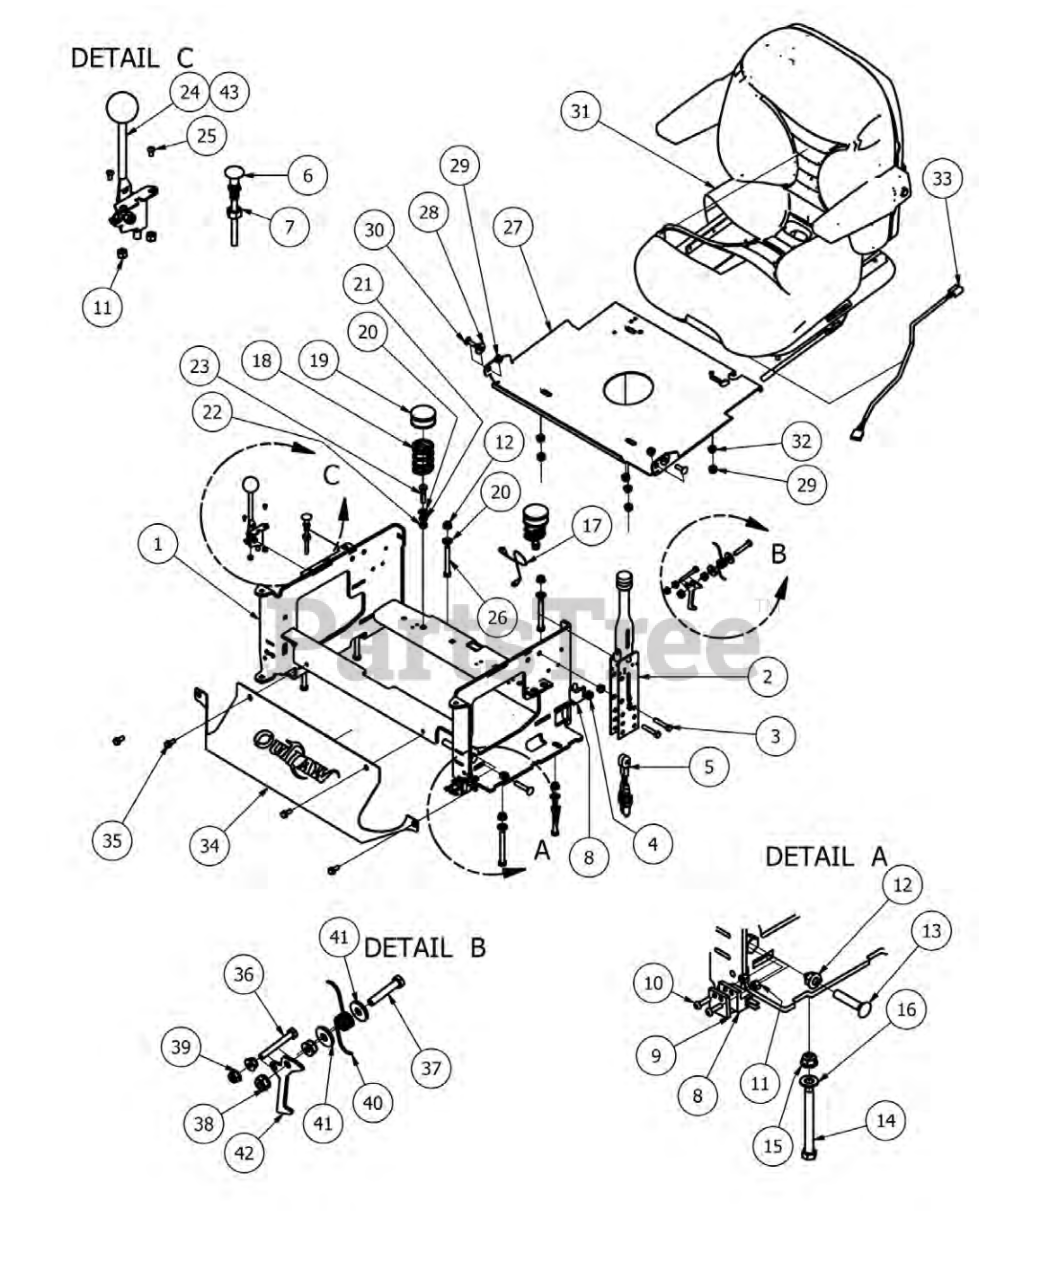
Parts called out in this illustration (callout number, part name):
1	Outlaw Seat Bracket 2012
2	Brake Handle Kit
3	5/16" x 1 3/4" Hex Bolt
4	5/16-18 Nylon Flange Nut
5	Long Brake Cable
7	3/8" Fine Threaded Jam Nut
8	Safety Switch
9	Switch Block Plastic
10	10-24 x 1 BS C/S 18-8 SS
11	10-24 Nylon Insert Locknut
12	3/8" Nylock Flange Nut
13	3/8 x 1 3/4 Carriage Bolt
14	3/8-16x3-1/2 grade 5 hex bolt
15	3/8" Nylock Flange Nut
16	3/8" Flat Washer
17	Seat Cable
18	Seat Spring
19	Spring Cap Cover
20	3/8" Flat Washer
21	3/8" Lock Washer
22	3/8" Hex Nut
23	3/8" x 1 1/2" Hex Bolt
24	Throttle-All Outlaws
25	10-24 X 5/8 BS C/S 18-8 SS
26	3/8-16x3 grade 5 hex bolt
27	Seat Plate
28	.360 ID Plastic Washer
29	5/16-18 Nylon Flange Nut
30	5/16" x 1" Carriage Bolt
31	2010 Outlaw Seat
32	5/16" Flange Nut
33	Seat Switch Adapter
34	Outlaw Cooler Cover
35	5/16 x 3/4 washer head type F screw
36	1/4-20 x 2 Hex Bolt
37	5/16" x 1 3/4" Hex Bolt
38	5/16-18 Nylon Flange Nut
39	1/4-20 Hex Flange Nuts Zinc w/Serrations
40	Torsion Spring for Seat latch
41	.360 ID Plastic Washer
42	Seat Latch Lever
43	Throttle for Kawasaki Models
